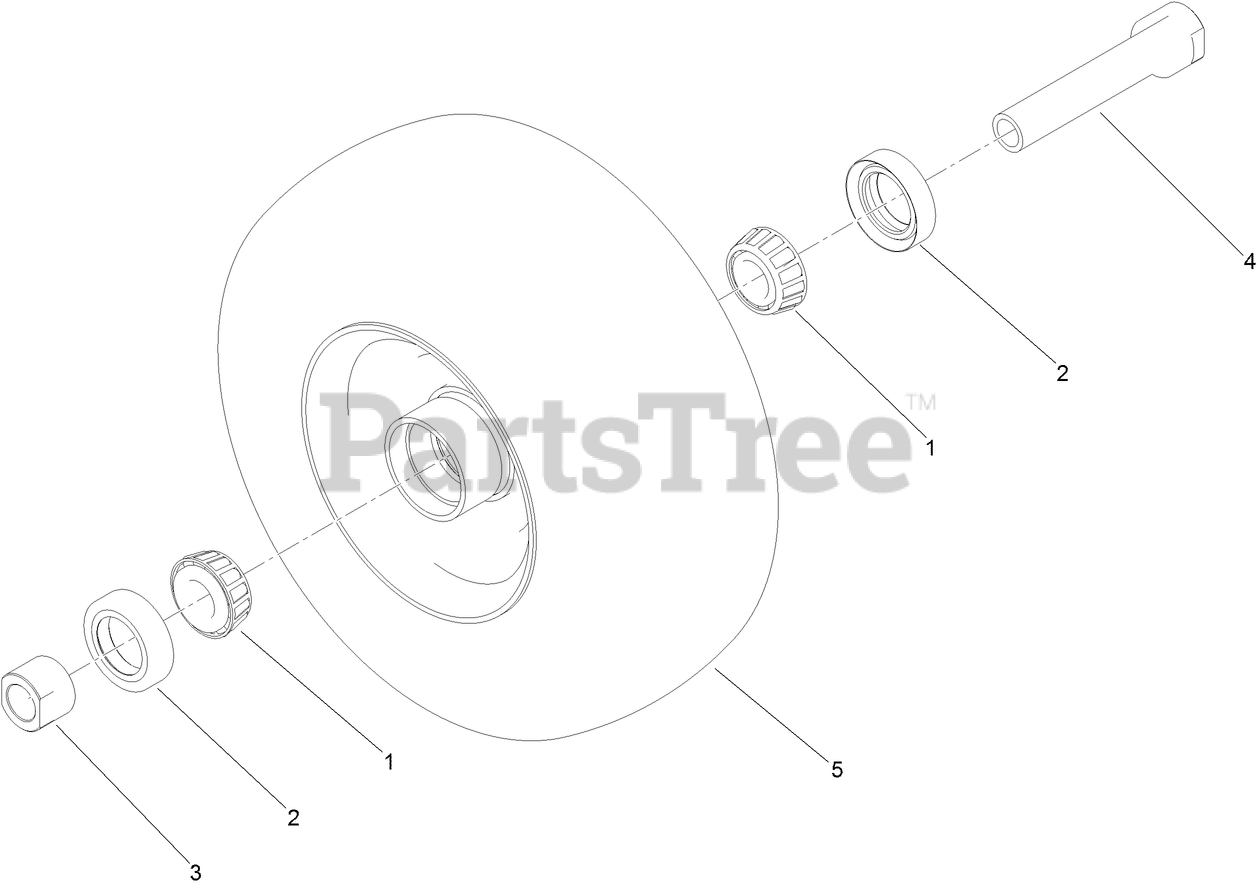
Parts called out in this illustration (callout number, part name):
1	BEARING-CONE, TAPER
2	SEAL-CASTER
3	SPACER-NUT
4	CASTER AXLE ASM
5	MF WHEEL AND TIRE ASM
